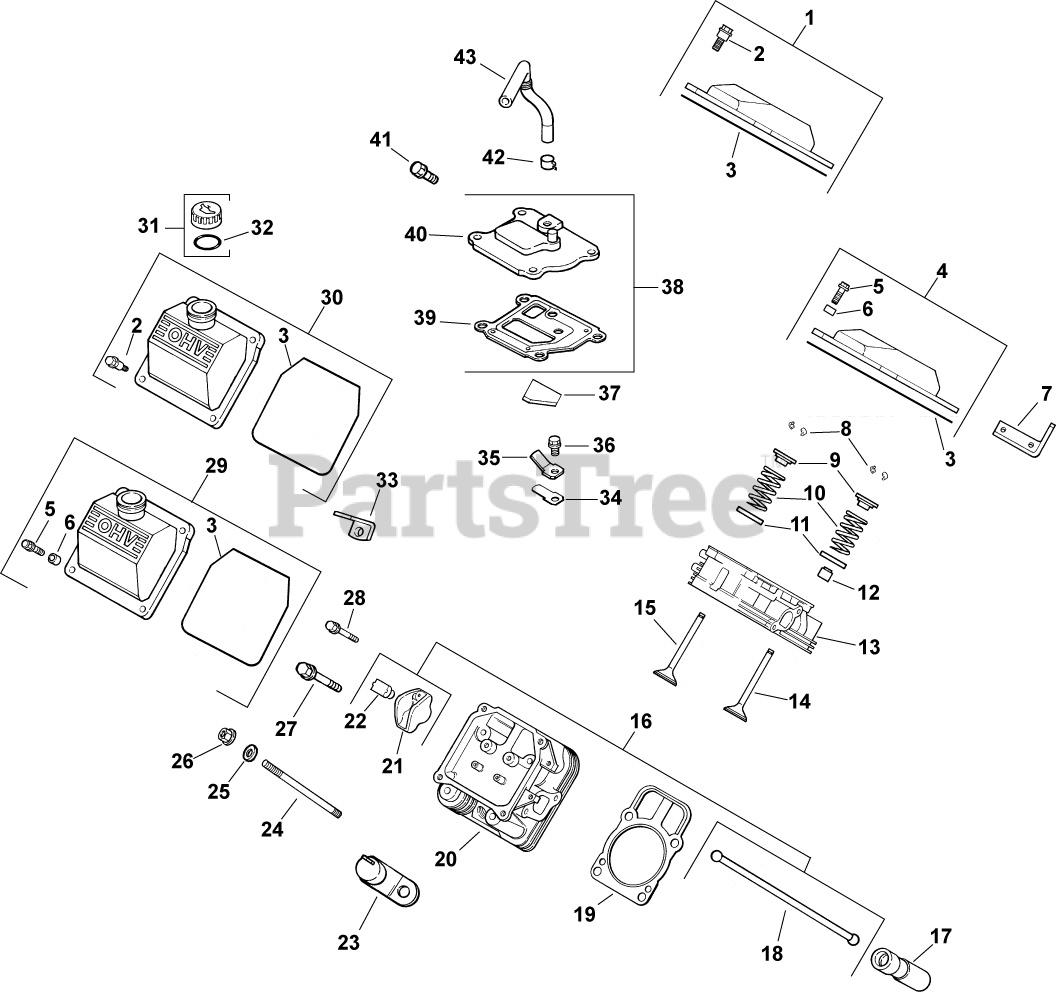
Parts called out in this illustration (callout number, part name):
1	KIT, VALVE COVER-PLAIN
2	SCREW, SHOULDER
3	O-RING (BLACK)
7	STRAP, LIFTING-USE 25 445 03-S
8	KIT, RETAINER
9	RETAINER, VALVE SPRING - USE 25 173 28-S
10	SPRING, VALVE
11	RETAINER, SPRING
12	SEAL, VALVE STEM - (#2503214S)
13	HEAD, SERVICE ASSY CYL #1-USE 24 318 106
14	VALVE, INTAKE (STD)
15	VALVE, EXHAUST (STD) - USE 32 016 01-S
16	KIT, VALVE TRAIN
17	LIFTER, HYDRAULIC VALVE-USE 25 351 10-S
18	ROD, PUSH
19	CYL HEAD GASKET KIT-USE 24 841 04-S
20	HEAD, SERVICE ASSY CYL #2-USE 24 318 114
21	ARM, ROCKER
22	PIVOT, ROCKER ARM
24	STUD, M8X1.25
25	WASHER, FLAT 8.6 MM
26	NUT, FLG M8X1.25
27	SCREW-USE 62 086 08-S
28	SCREW, FLG M6X1.0X34
30	KIT, VALVE COVER-OIL FILL
31	KIT, OIL FILL CAP (BLACK)
32	O-RING, DIPSTICK
34	REED, BREATHER
35	RETAINER, REED
36	SCREW, FLG THD FRM M5X.8X10
37	FILTER, BREATHER-USE 24 050 11-S
38	KIT, BREATHER ASSEMBLY
39	GASKET, BREATHER-USE 24 041 67-S
40	COVER, BREATHER -USE 24 033 01-S
41	SCREW,FLG THD FRM M6X1.0X20-(#25086396S)
42	CLAMP, HOSE (KM)-USE 25 237 31-S
43	HOSE, BREATHER-USE 24 326 89-S
2401602-S	VALVE, EXHAUST (.25)
2401702-S	VALVE, INTAKE (.25)
